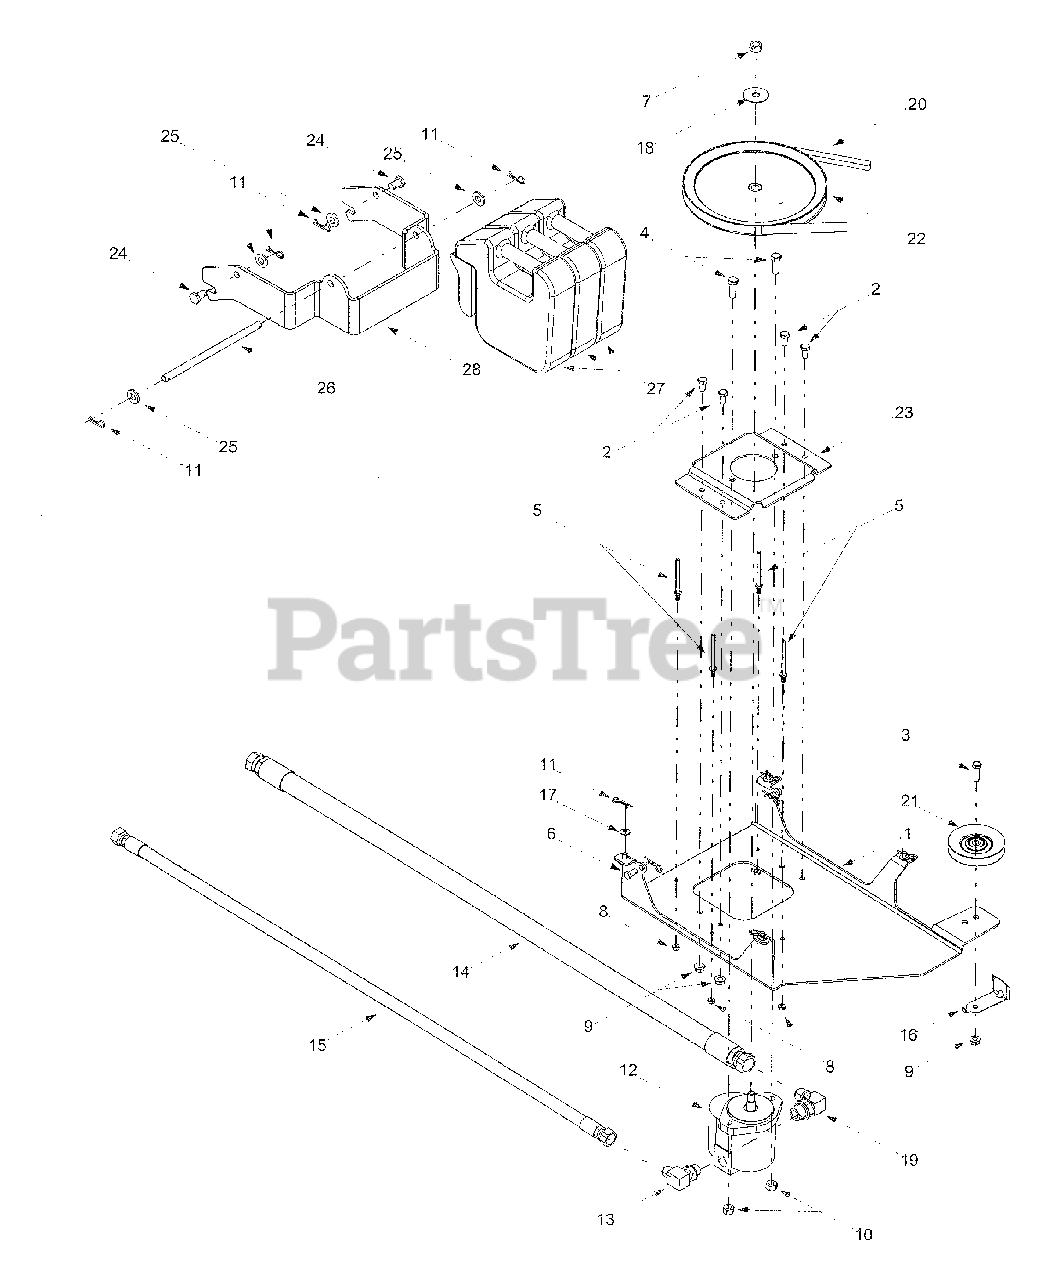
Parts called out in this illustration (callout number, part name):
3	Hex Cap Screw, 3/8-16 x 1.25
4	Hex Cap Screw, 7/16-20
5	Belt Keeper Pin
6	Clevis Pin, 3/8 x .75
7	Hex Lock Nut, 1/2-20
8	Hex Lock Nut, 1/4-20
9	Hex Lock Nut, 3/8-16
10	Hex Lock Nut, 7/16-20
11	Click Pin, .092 x 1.64
12	Eaton Hydraulic Pump (Includes key)
13	90 degree Hydraulic Adapter, 7/8
14	Hydraulic Hose, 1.0625-12 x 54
15	Hydraulic Hose, .875-14 x 49
16	Belt Guard
17	Flat Washer, .344 x .688
18	Flat Washer, .531 x 1.75
19	90 degree Hydraulic Adapter
20	V-belt
21	Idler Pulley, 5/8 x 4.0
22	Drive Pulley, 10.0
23	Pump Mounting Bracket
24	Clevis Pin, .5 x .78
25	Flat Washer, .531 x 1.062
26	Weight Guard Rod
27	45 lb. Suitcase Weight
